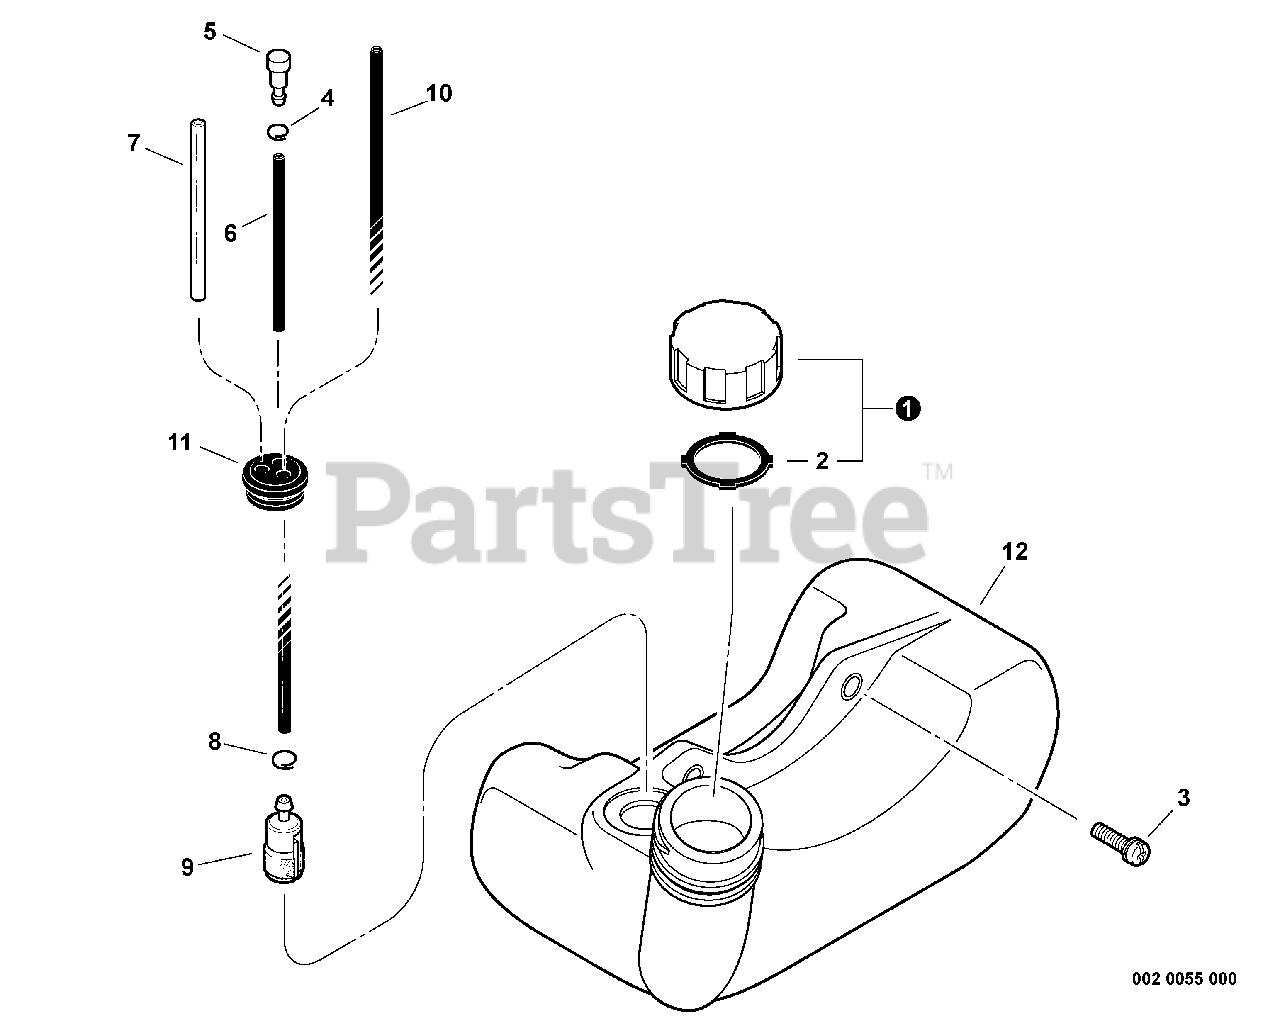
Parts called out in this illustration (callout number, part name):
1	CAP ASSY
2	GASKET, CAP
3	SCREW - 5X20
4	CLIP - 5.5
5	VENT, FUEL TANK
6	PIPE - 3X5X70 -- BLACK
7	PIPE - 3X6X70 -- CLEAR
8	CLIP - 6
9	FILTER, FUEL
10	PIPE - 3X5X180 -- BLACK
11	GROMMET
12	TANK, FUEL
